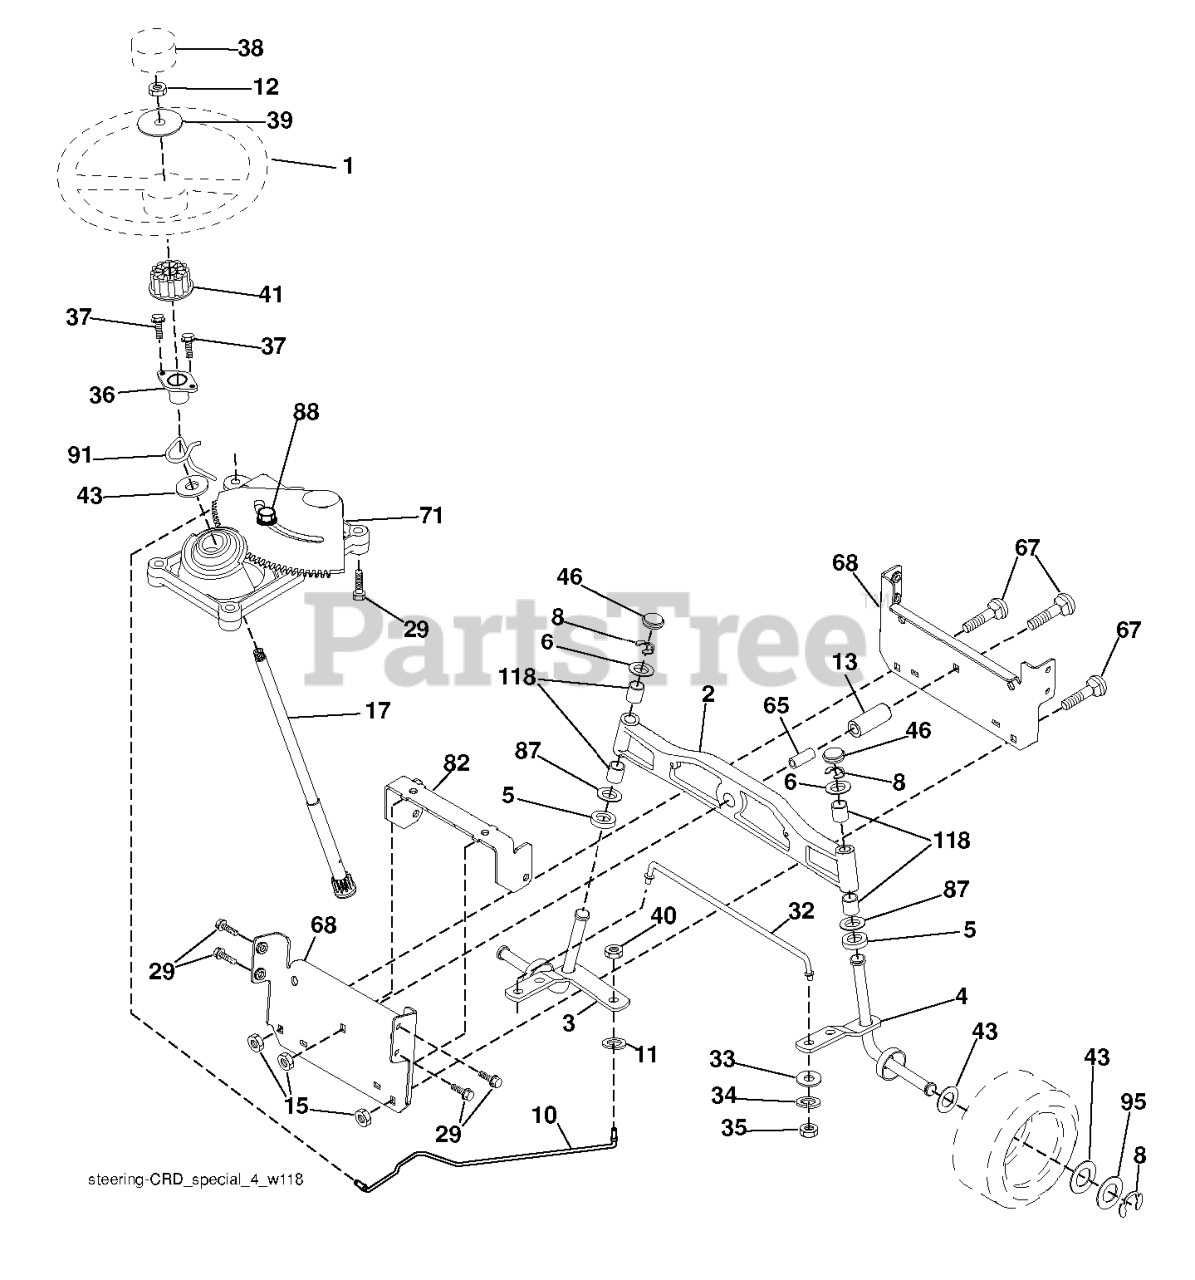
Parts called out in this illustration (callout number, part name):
1	RP WHEEL.STEER.HUSQ.PREM.OVMLD
2	AXLE.ASM.LT.CAST.LGHTWGHT
3	SPINDLE.ASM.LH.15"TIRES
4	SPINDLE.ASM.RH.15"TIRES
5	THRUST WASHER
10	DRAGLINK.15".TIRES.2001
11	WASHER, LOCK 3/8
12	NUT.HEX.1/2-20
13	TUBE, PIVOT AXLE
15	NUT
17	SHAFT ASM STRG
29	SCREW, 3/8-16X3/4
33	WASHER M
34	WASHER.LOCK.HVY.HLCL.SPR.5/16
35	NUT, CROWNLOCK
36	BUSHING, STRG. BLK
37	SCREW.TT.#10-32X.5.3/8.FLANGE
38	RP INSERT.CAP.WHL.STRG.HUSQ.
39	WASHER 9/16"ID, 2 3/8"OD
40	NUT CROWNLOCK 3/8-24
41	ADAPTER, WHEEL STNG..
46	CAP.SPINDLE.BLACK
65	SPACER.BRACE.AXLE
67	BOLT CARRIAGE
68	BRACE.AXLE.15"TIRES
71	STEERING ASM
82	BRACKET.SUSP.CHASSIS.FRONT.15
87	WASHER, FLAT .781 X 1 1/2"
88	BOLT, SHOULDER 7/16-20
91	CLIP.STEERING
95	WASHER.HARDENED
118	BUSHING, AXLE CAST
